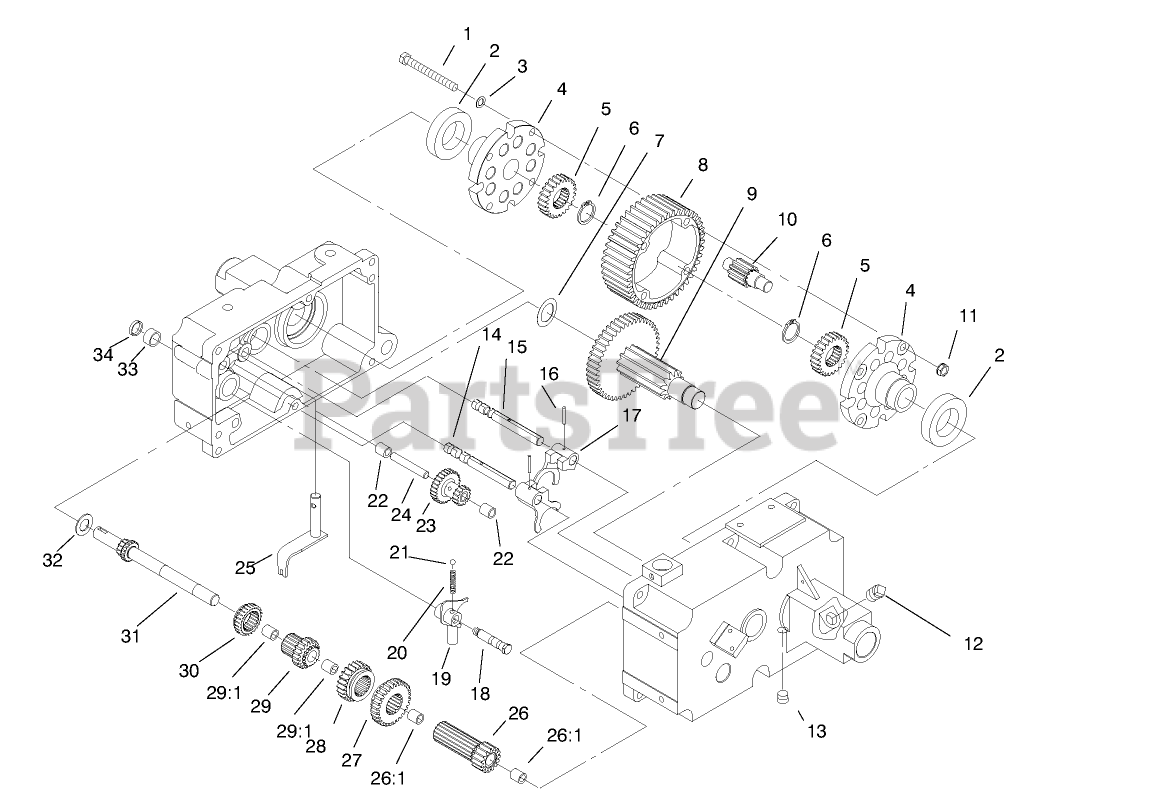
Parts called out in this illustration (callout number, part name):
2	BEARING-BALL
3	WASHER
4	END CAP-DIFFERENTIAL
5	GEAR-AXLE DIFFERENTIAL
6	RING-SNAP
7	WASHER-THRUST
8	GEAR-DIFFERENTIAL RING, 43T
9	GEAR ASM
10	GEAR-PINION, 11T
11	NUT-HEX
12	PLUG-PIPE, SQH
14	RAIL-SHIFT
15	RAIL-REAR SHIFT
16	PIN-ROLL
17	FORK-SHIFT
18	BOLT-DETENT
20	SPRING-SHIFT STOP
21	BALL-DETENT
22	BEARING-NEEDLE
24	GEAR-SHAFT REDUCTION
25	SHIFT ASM
25:1	Shift Lever
25:2	Shaft-Lever
26	GEAR
26:1	BEARING-NEEDLE
27	GEAR-LOW AND REVERSE
28	GEAR-HI AND 2ND
29	GEAR
29:1	BEARING-NEEDLE
30	GEAR-SLIDING
31	SHAFT-INPUT
32	WASHER-THRUST
33	BEARING-NEEDLE
34	SEAL-OIL
